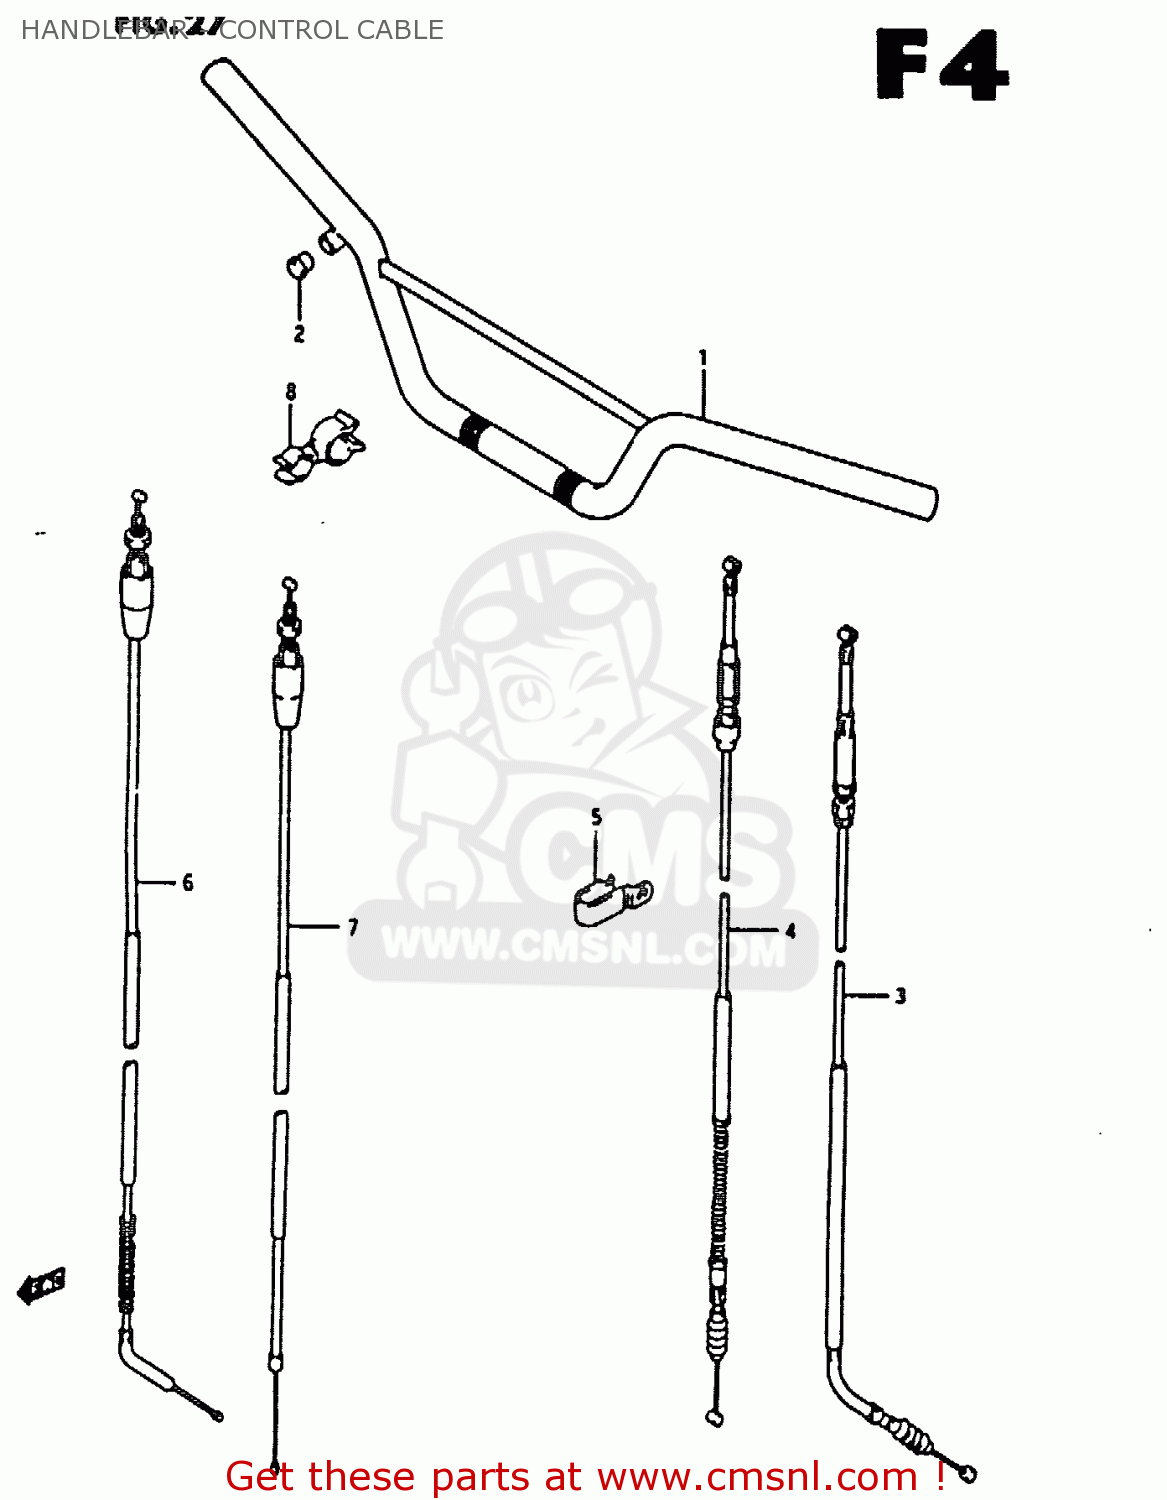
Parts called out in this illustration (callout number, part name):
1	HANDLEBAR
2	CAP(OD:14)
3	CABLE ASSY,CLUTCH
4	CABLE ASSY,CLUTCH
5	CLAMP
6	CABLE ASSEMBLY,THROTTLE
7	CABLE ASSEMBLY,THROTTLE
8	CLAMP
